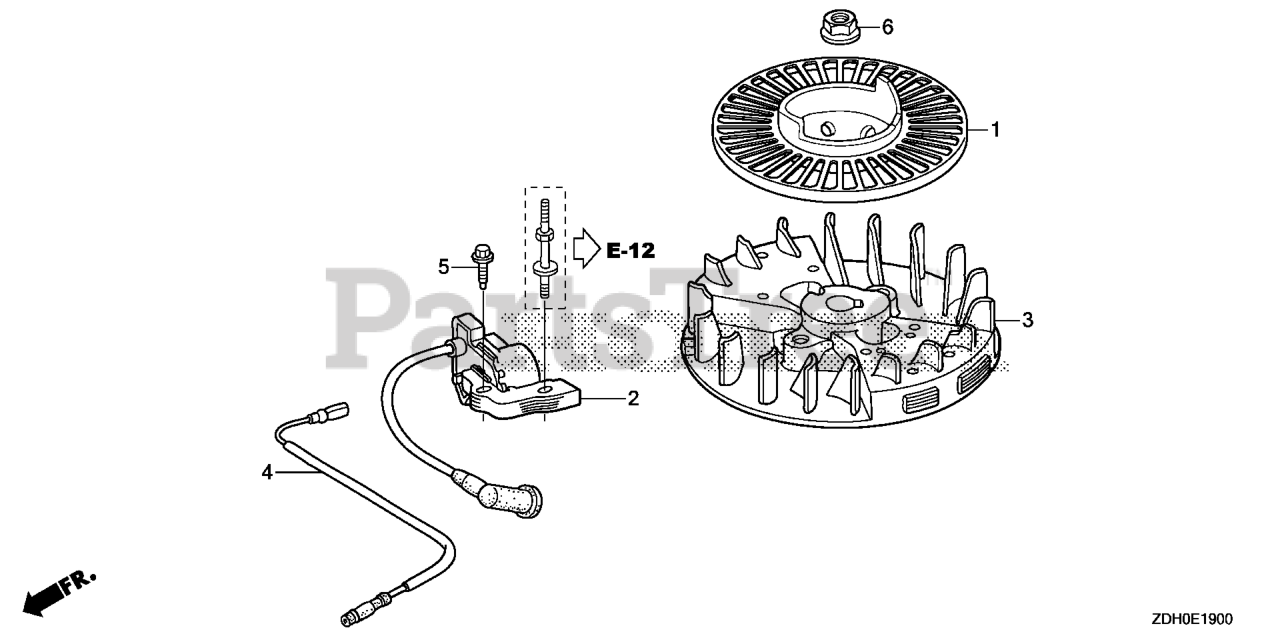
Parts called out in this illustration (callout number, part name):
1	PULLEY, STARTER
2	COIL ASSY., IGNITION
4	WIRE, STOP SWITCH
5	BOLT, FLANGE (5X20)
6	NUT, FLANGE (10MM)
